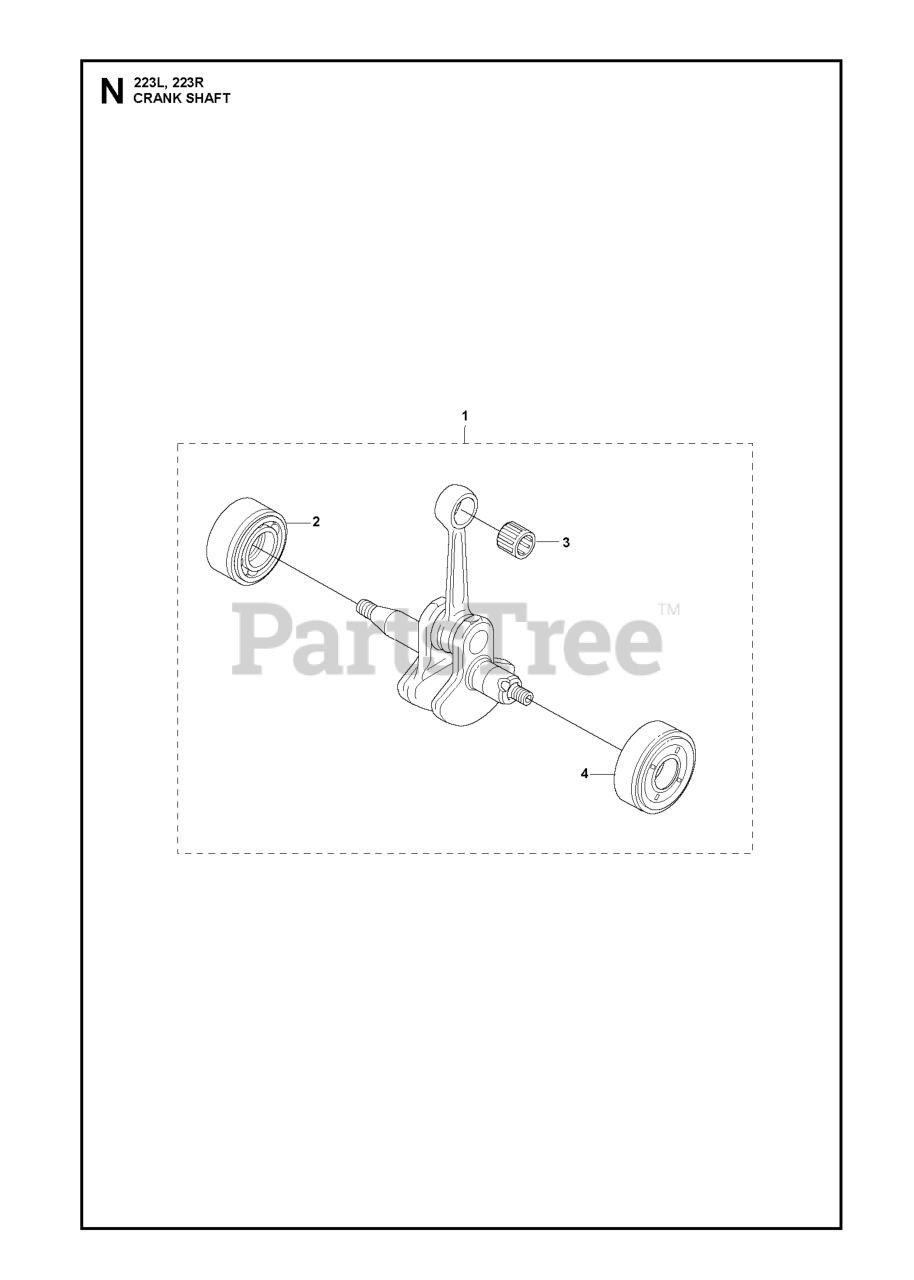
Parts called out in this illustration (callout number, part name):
1	CRANKSHAFT
2	BEARING CAP
4	BEARING CAP
